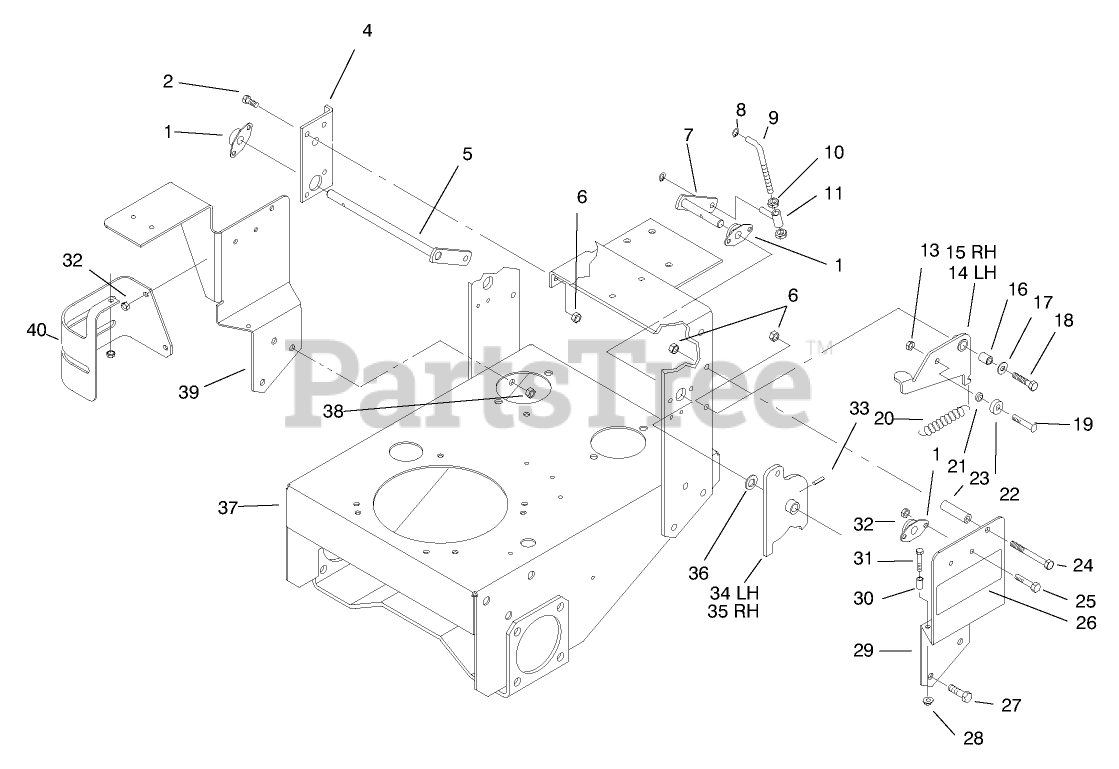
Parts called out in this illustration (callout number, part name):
1	SIDE FLANGE BEARING ASM
2	SCREW-HH
3	TIE-CABLE
4	BRACKET-BUSHING
5	LEVER-PIVOT, RH
6	NUT-LOCK, NI
7	LEVER-PIVOT, LH
8	RING-GRIP
9	ROD-LINK
10	NUT-JAM
11	SLEEVE
13	NUT-LOCK, NI
14	ARM-DETENT, LH
15	ARM-DETENT, RH
16	BUSHING-ARM, DETENT
17	WASHER-PLAIN
18	SCREW-HH
19	SCREW-HSBH
20	SPRING-DETENT
21	SPACER-BEARING
22	BEARING-BALL
23	STOP-REVERSE
24	SCREW-HH
25	SCREW-HH
26	DECAL-HYDRO
27	SCREW-HH
28	NUT-LOCK, HHF
29	BRACKET-PIVOT, LH
30	SPACER-TUBULAR
31	SCREW-HH
32	NUT-LOCK, NI
33	PIN-ROLL, SLOTTED
34	ARM-PIVOT, LH
35	ARM-PIVOT, RH
36	WASHER-THRUST
37	FRAME WA
38	NUT-LOCK, NI
39	BRACKET-PIVOT, RH
40	GUARD-FILTER
